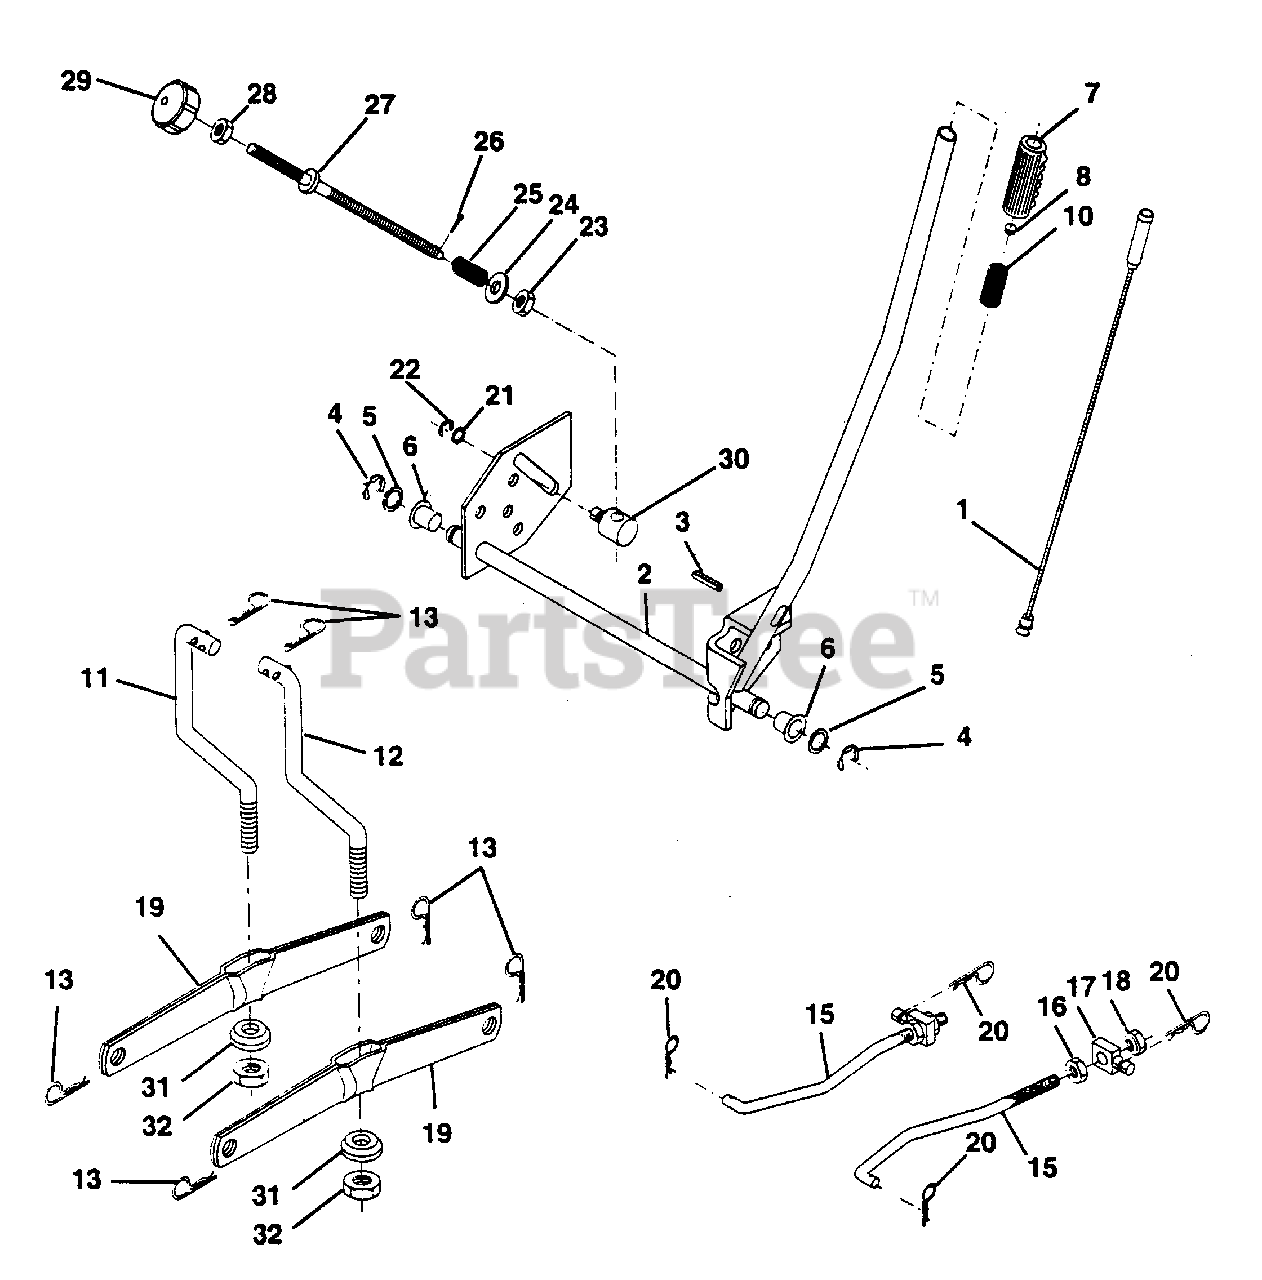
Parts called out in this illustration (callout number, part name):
1	Wire Asm Inner W/plunger 20 56
2	Shaft Asm Lift RH w/Inf
3	Pin Groove 1 500 Zinc
4	E Ring #5133-62
5	Washer 21/32 X 1 X 21 Ga
6	Bearing Nylon Blk 629 Id
7	Grip Handle Bicycle Blk
8	Button Plunger Black
10	Spring Cprsn 3 750 Oiled
11	Link Lift LH
12	Link Lift RH
13	Retainer Spring
16	Nut Jam Hex 1/2-13 Unc
17	Trunnion Blk Zinc
18	Nut Lock W/wsh 1/2-13unc
19	Arm Suspension Rear
20	Retainer Spring
21	Washer 15/32 X 3/4 X 16 Ga
22	Ring Klip #t5304-37
24	Washer 13/32 X 5/8 X 16 Ga
25	Spring 2-1/8"
26	Pin Cotter 3/32 X 1/2
27	Rod Adj Lift Zinc 9 00 Wrk Lg
28	Nut Hex Jam 3/8-16 Unc
29	Knob Inf 3/8-16 Unc Blk W/sym
30	Trunnion Dp Stop Dbl Thds PLT
31	Bearing Pvt Lift Spherical
32	Nut Lock 3/8-24 w/Nylon Insert
